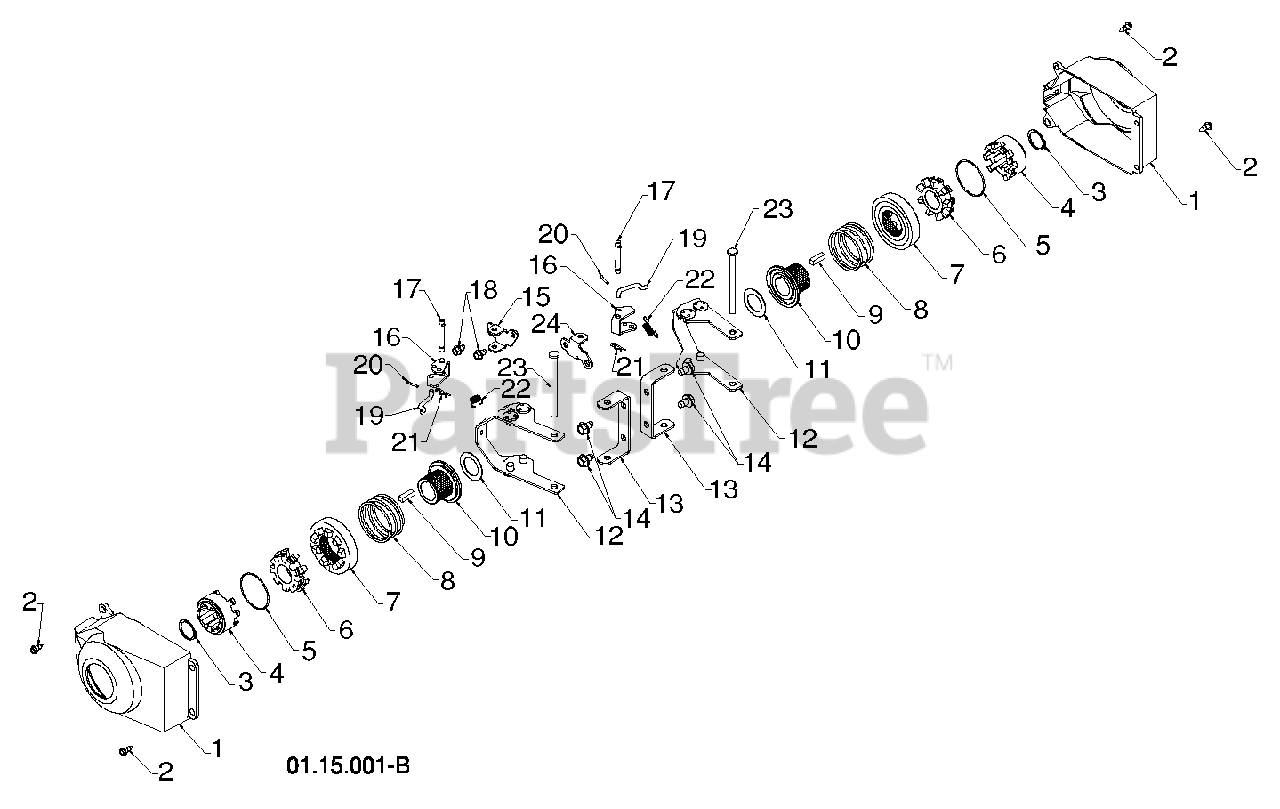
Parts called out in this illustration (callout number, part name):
1	COVER, POWER STEERING
2	SCREW, HEX HEAD, TAPPING
4	DRIVER WHEEL
5	RING, WIRE RETAINER
6	LOBE WHEEL
7	SLIDE.CLUTCH
8	SPRING, CLUTCH SLIDE
9	KEY, SQUARE 1/4 X .875
10	LOBE.AXLE
11	WASHER 1.00
12	YOKE.WELDMENT.STEER.BLACK
13	BRACKET.STEER.PNT.BLACK
14	SCREW LT
17	PIN, STEERING BELLCRANK
18	SCREW 1/4X20
19	LINK.STEER.YOKE
20	RETAINER CLIP
21	RETAINER CLIP PM
22	SPRING LATCH
23	PIN, STEERING LEVER
